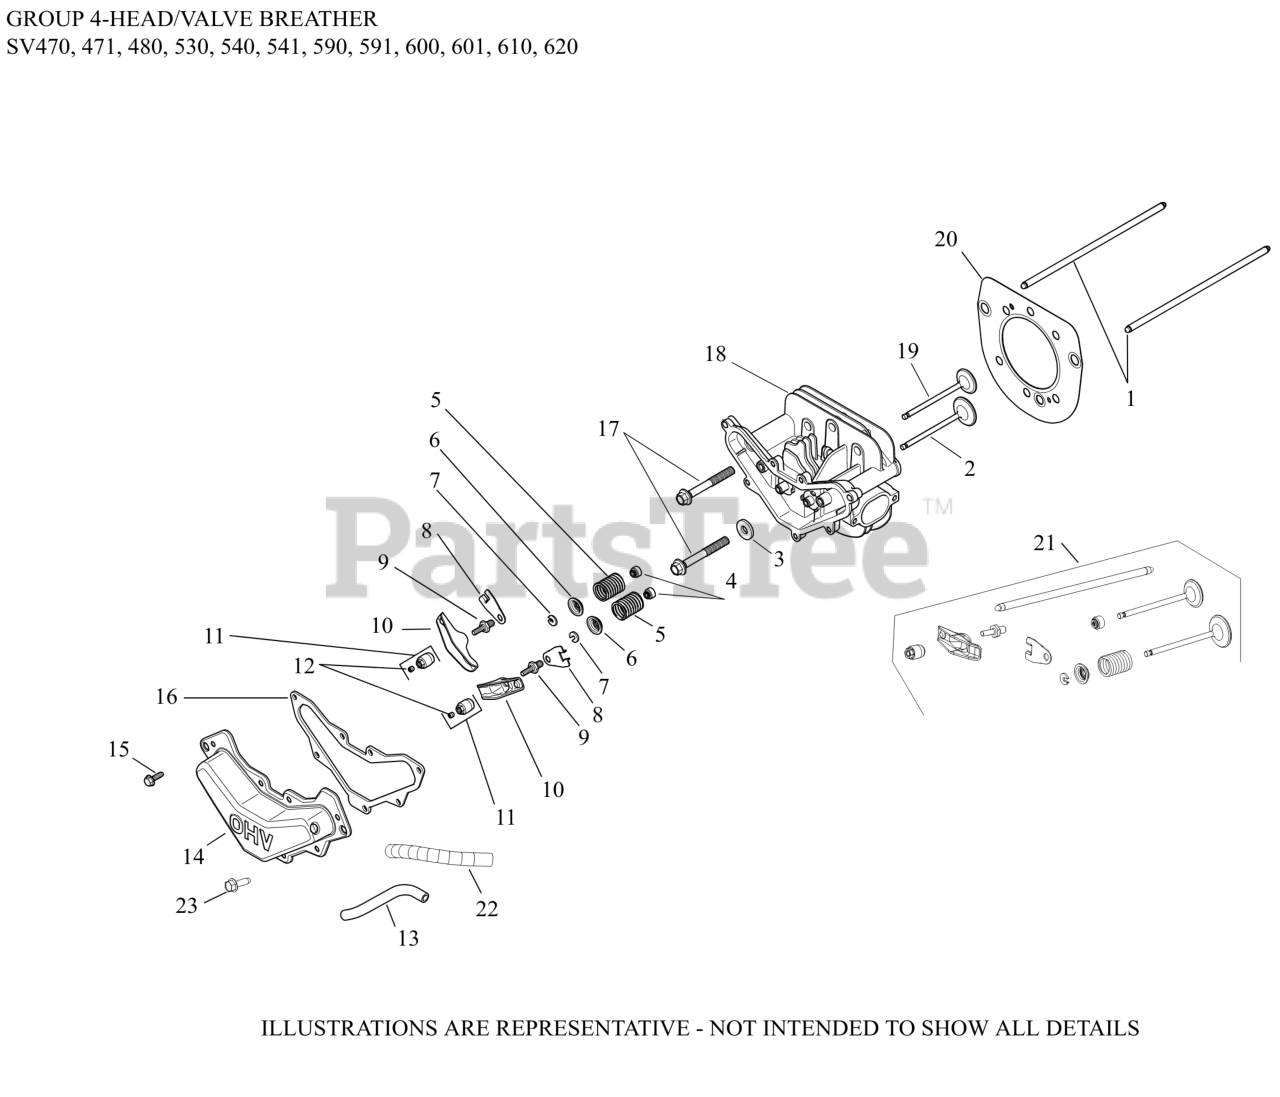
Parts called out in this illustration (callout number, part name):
1	ROD, PUSH
2	VALVE, INTAKE
3	WASHER, FLAT 13/32"
4	SEAL, VALVE STEM
5	SPRING, VALVE
6	CAP, VALVE SPRING
7	LOCK, RETAINER
8	PLATE, PUSH ROD GUIDE
9	STUD, ROCKER
10	ARM, ROCKER
11	PIVOT, ROCKER ARM-USE 20 599 04-S
11	ROCKER PIVOT ASSY
12	SCREW, SET
13	HOSE, BREATHER-USE 20 094 11-S
14	COVER, VALVE ASSEMBLY - USE 20 096 14-S
15	SCREW,FLG THD FRM M6X1.0X20-(#25086396S)
16	GASKET, VALVE COVER
17	SCREW, CYLINDER HEAD (M10 X 80)
18	KIT, CYLINDER HEAD
19	VALVE, EXHAUST
20	KIT, CYLINDER HEAD GASKET
21	KIT, CYLINDER HEAD HARDWARE
